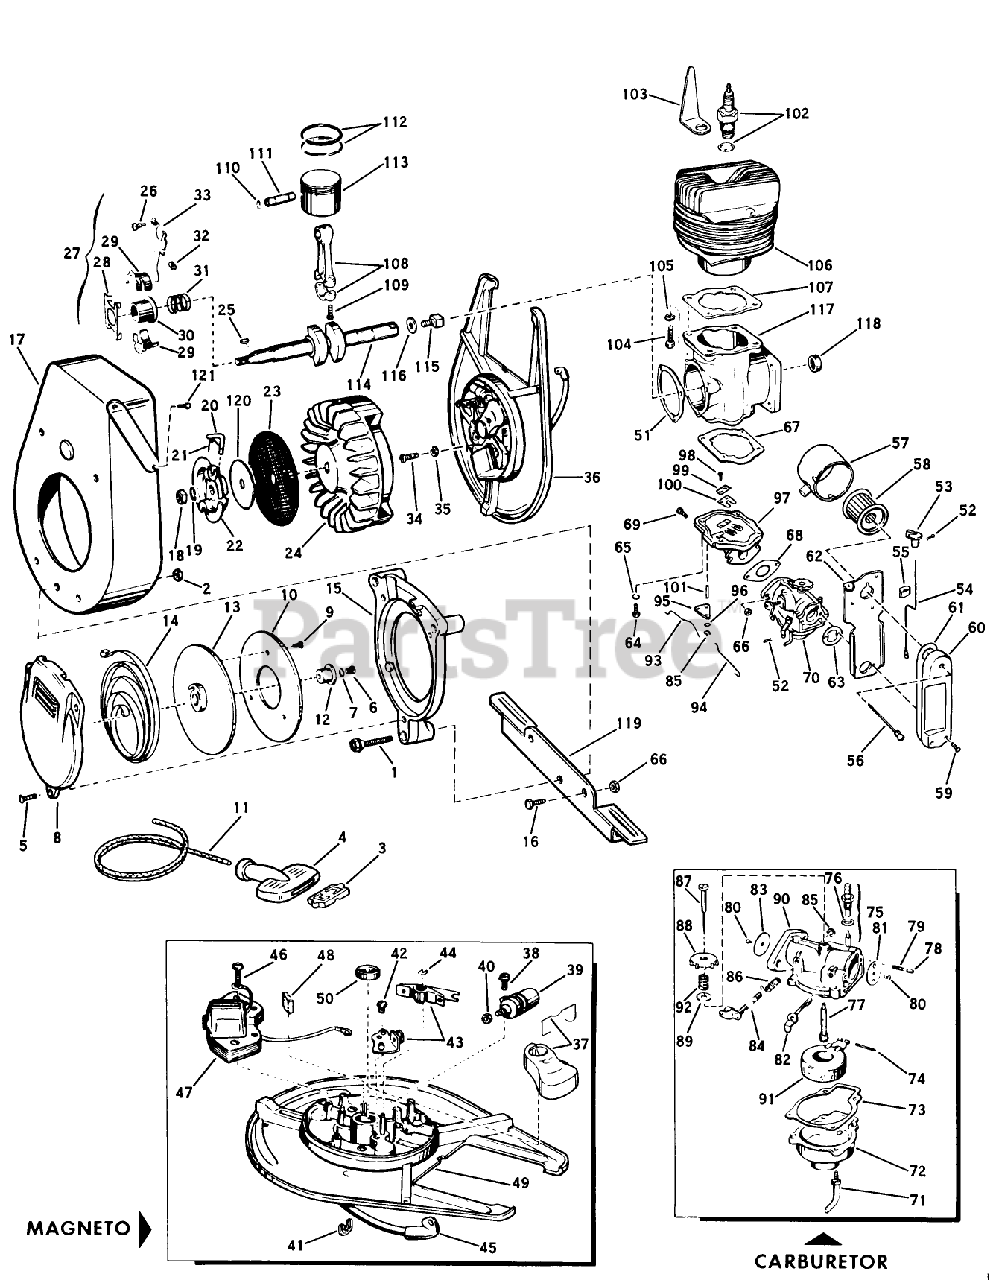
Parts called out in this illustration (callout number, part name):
10	Plate-Pulley
11	Rope-Starter
14	RECOIL SPRING
16	SCREW S
20	PIN - STARTER
30	COLLAR S
31	Spring-Governor
32	WEAR BLOCK S
33	GOVERNER LEVER AY
43	BREAKER AY. S
51	GASKET S
52	Cotter Pin
53	KNOB, CHOKE BAR
54	Choke Rod
55	Spring Clip
56	Screw-Thumb
59	Screw-Sems
60	Chamber-Intake
61	Gasket-Intake Chamber
62	Plate-Filter Attachment
64	SCREW S
67	Gasket-Reed Plate to Crankcase
68	GASKET S
69	SCREW S
71	Screw-Float Bowl to Carb.
80	Screw-Choke Disc
86	Spring-Throttle Shaft
87	NEEDLE AY. S
90	Carburetor Body
92	Spring-Ndl. Adj.
93	Rod-Governor
94	Link-Throttle
95	Bell Crank
99	PLATE-BACKUP, REED
101	Roll Pin
102	Spark Plug
106	Cylinder Sleeve Assembly
107	Gasket-Cylinder to Crankcase
109	Screw-Connecting Rod
112	Ring-Piston
114	Crankshaft
115	Screw-Square Head
119	Bracket-Wheel Scraper
121	SCREW S
